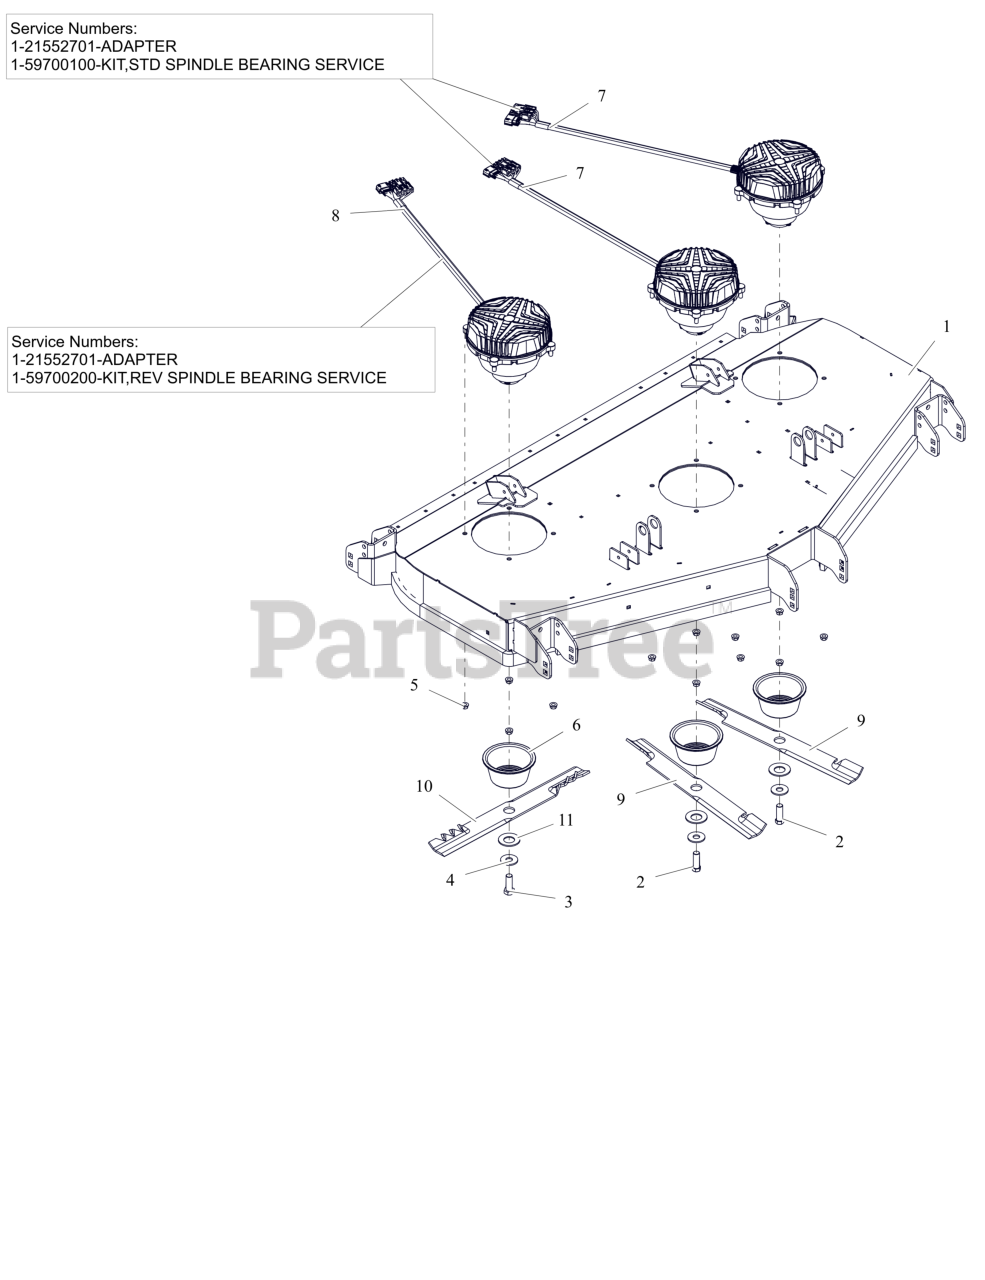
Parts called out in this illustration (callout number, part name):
1	KIT,DECK-60R W/DECALS-GRAVELY
2	BLT, HEX .62-18X1.75 G8 ZCC
3	BLT, HEX 0.625-11X1.75 GR8 ZCC LH
4	WSHR, HRDN 0.687X1.75X0.134 HRD
5	NUT-LK-CTR-FLG .375-16 GF ZCC
6	GUARD, SPINDLE LOWER
7	MOTOR, SPINDLE-CW
7	ADAPTER
7	KIT, STD SPINDLE BEARING SERVICE
8	MOTOR, DECK SPINDLE -CCW
8	ADAPTER
8	KIT,REV SPINDLE BEARING SERVICE
9	BLADE, 20.5" EVZT FLAT RD
10	BLADE, MOWER 20.5" TOOTHED CCW
11	WSHR, BLVL - .56X28.5X3 PHOS.COAT
